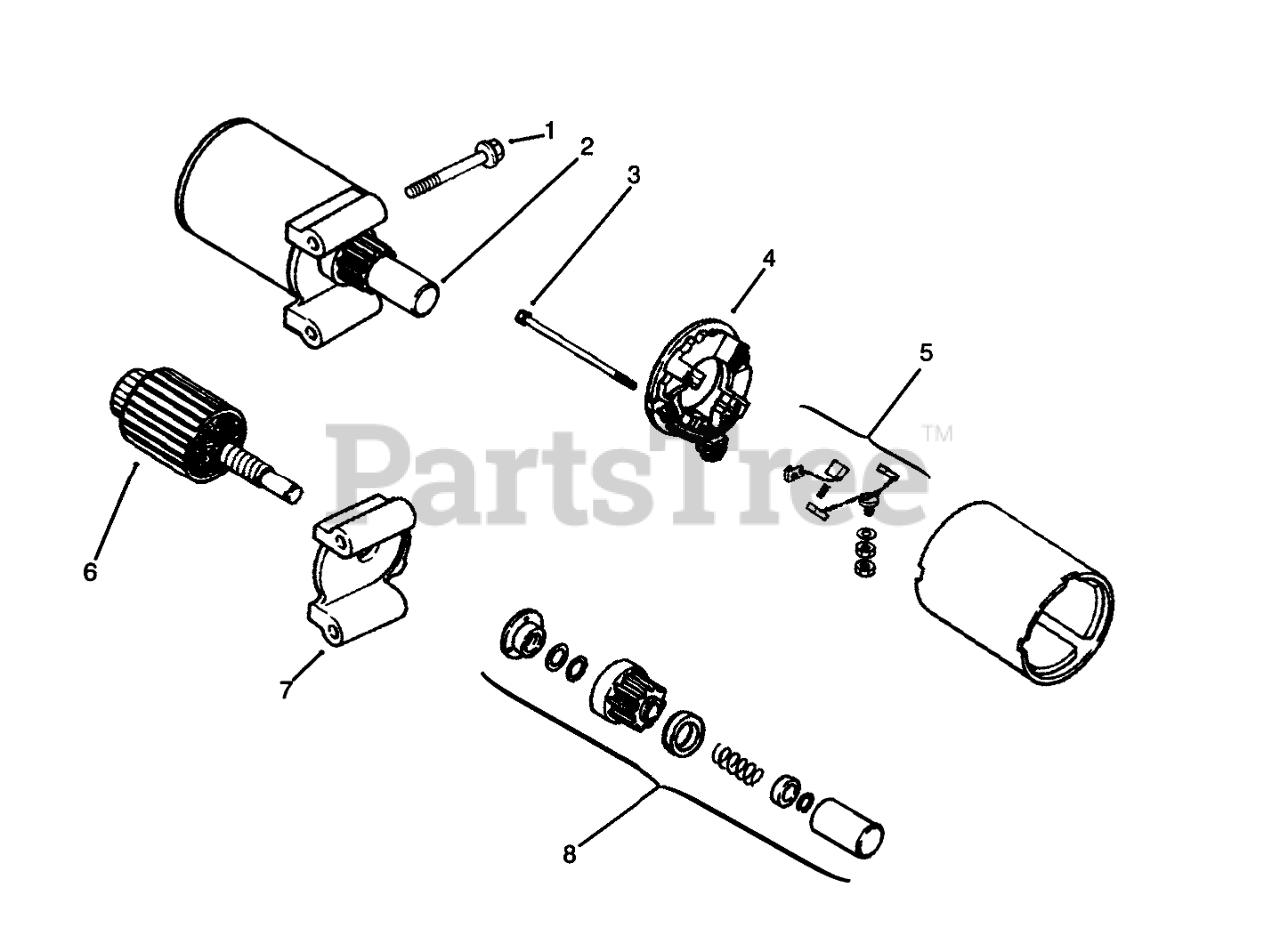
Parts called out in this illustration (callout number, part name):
1	Screw M8x1.25x70
2	Starter ASM Incl 3-8
3	Screw-HF
4	Cap-Commutator Incl 5
5	Kit-Brush And Spring
6	Armature-Starter
7	Cap-Drive End
8	Kit-Drive
